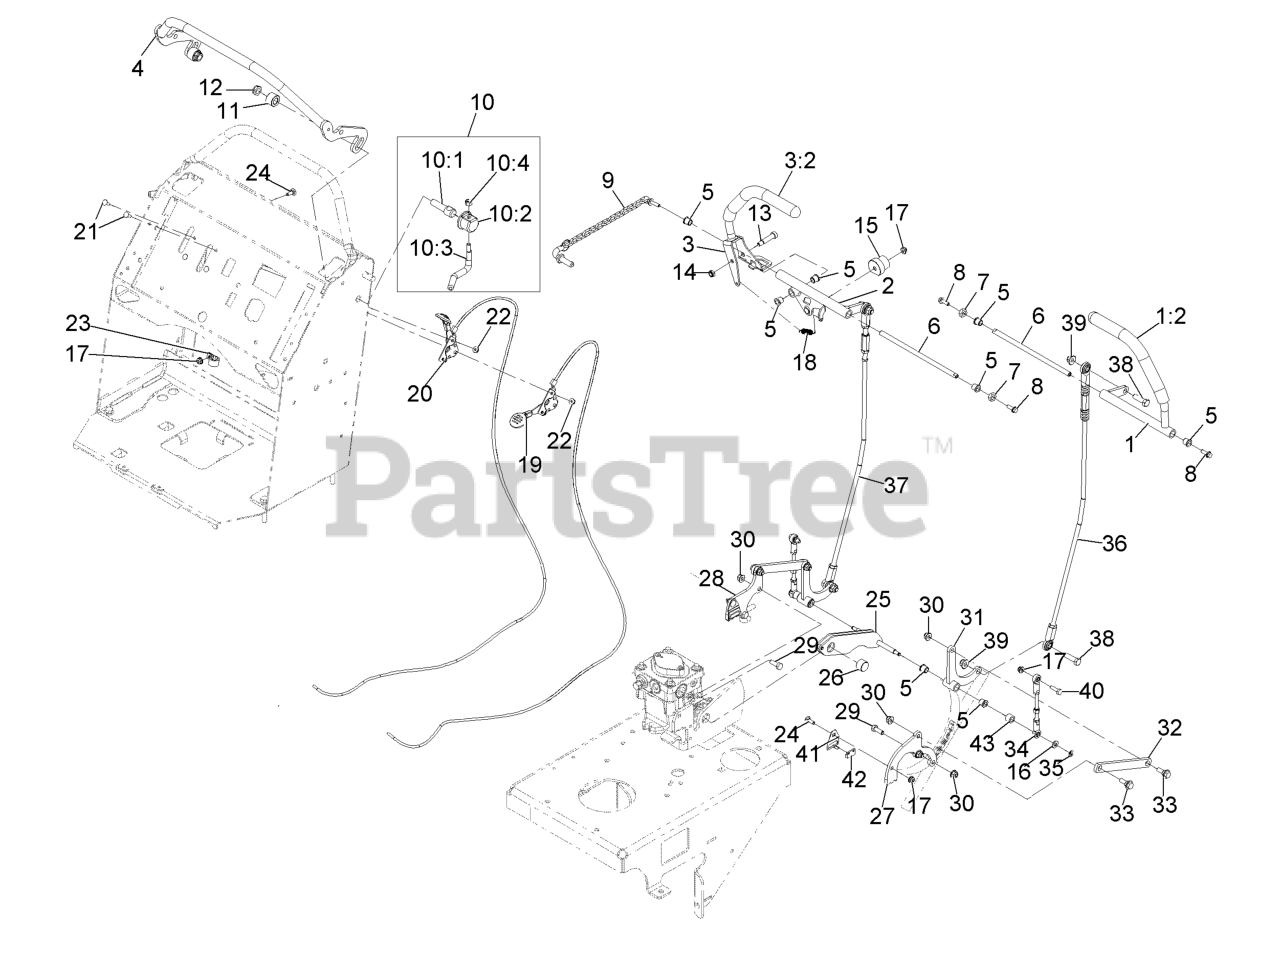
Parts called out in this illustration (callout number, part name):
1	Lever ASM, LH
1:2	Grip-Handle, Control
2	Weld, Motion Control
3	ASM, Lever W/ Grip, Rt
3:2	Grip-Handle, Control
4	Tube ASM, Front Speed Control [
5	Bearing
6	Shaft-Pivot, Motion Control
7	Spacer-Shaft, Drive Lever
8	Screw-Hex Flange 1/4-20 X 3/4
9	HOC Pin ASM
10	Lever ASM
10:1	Screw-Lock
10:2	Cap-Lock
10:3	Lever-Lock
10:4	Nut-Nyloc 5/16-18
11	Spacer-Clamp
12	Nut-Nyloc 1/2-13 Thin
13	Screw-Shoulder 5/16-18 X 1/2
14	Nut-Nyloc 5/16-18 Thin
16	Washer-1/4 SAE
17	Nut-Nyloc 1/4-20 Flg
18	Spring-Extension
19	Control-Throttle
20	Control-Choke
21	Bolt-Carriage #10-24 X 5/8
22	Nut-Whizlock #10-24
23	Clamp-Cable
24	Bolt-Carriage 1/4-20 X 3/4
25	Bellcrank Link ASM
26	Pin-Bellcrank Link Retaining
27	Arm-Pump Control
28	Arm-Pump Control RH
29	Screw-HH 5/16-18 X 7/8
30	Nut-Nyloc 5/16-18 Flg
31	Bellcrank-Lower
32	Link-Bellcrank, Pump
33	Screw-Shoulder HHF 5/16-18 X .96
34	Vertical Adjust Link
36	Linkage-Tracking Control, LH
37	Linkage-Tracking Control, RH
38	Screw-HH 3/8-16 X 1 1/4
39	Nut-Nyloc 3/8-16 Flg
40	Screw-HH 1/4-20 X 7/8
41	Clamp-Switch
42	Actuator-Switch, Reed
43	Spacer-Wheel
